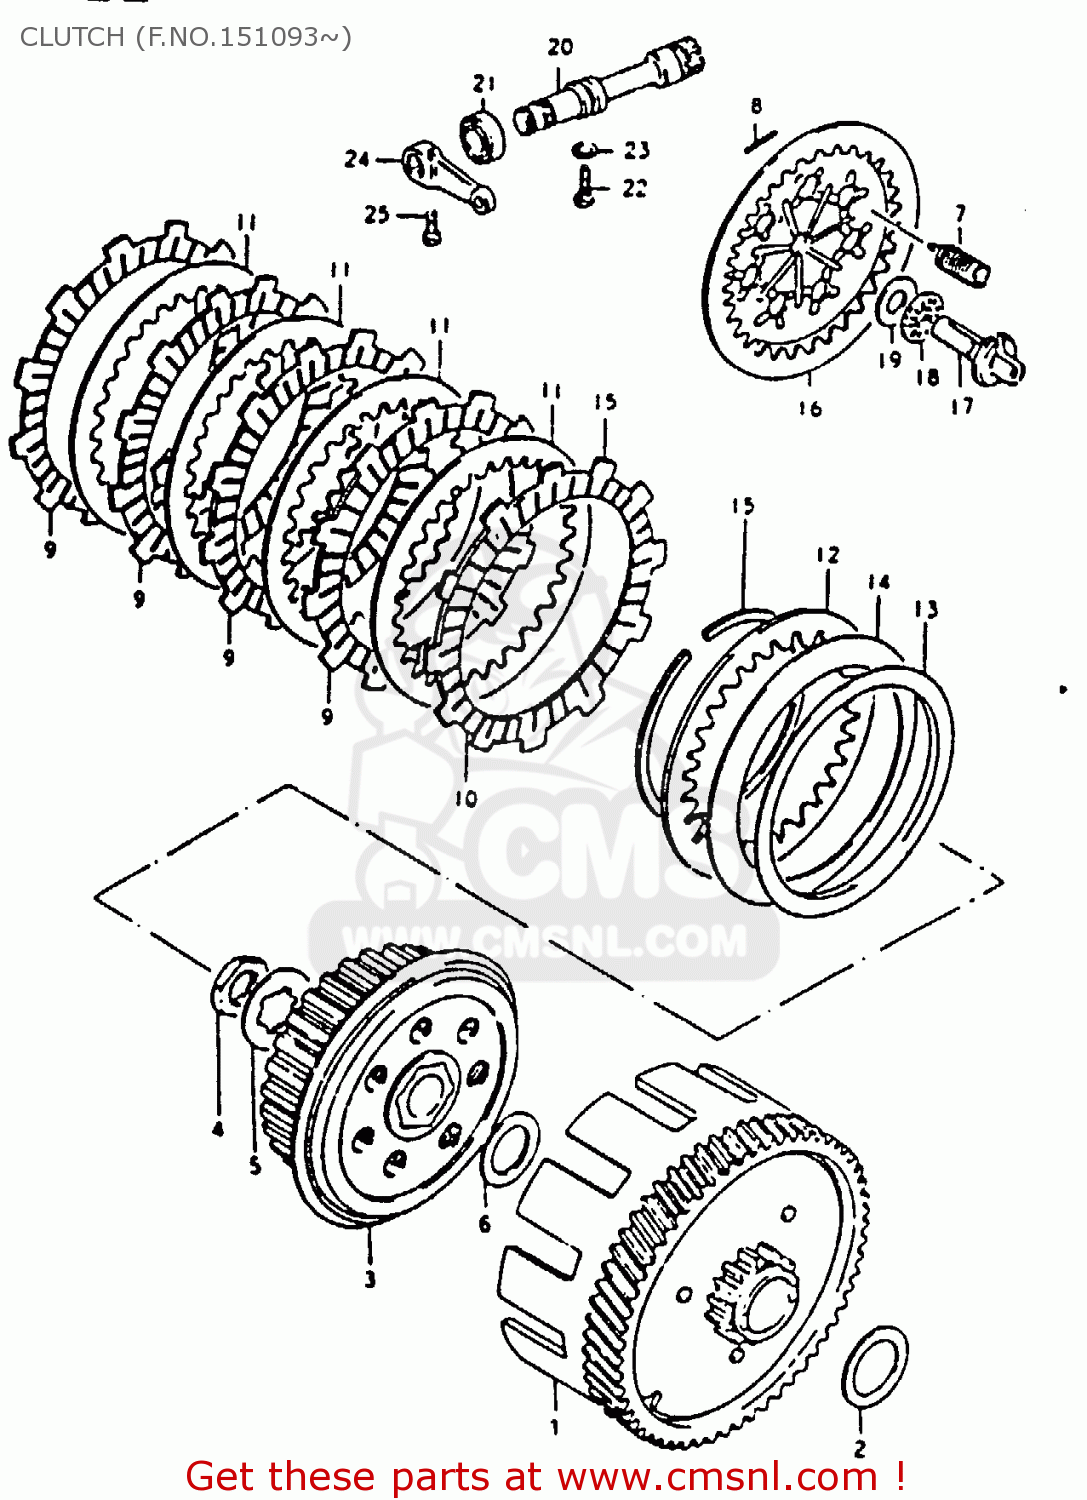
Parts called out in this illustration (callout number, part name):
1	GEAR ASSEMBLY,PRIMARY DRIVE
2	WASHER
3	HUB,CLUTCH SLEEVE
4	NUT
5	WASHER,LOCK
6	WASHER
7	SPRING
8	PIN(2.5X19.8)
9	PLATE,CLUTCH DRIVE
10	PLATE,CLUTCH DRIVE (MCA)
11	PLATE,CLUTCH DRIVEN (NAS)
12	PLATE,CLUTCH DRIVEN(T:2.0) (NAS)
13	SEAT,WAVE WASHER
14	WASHER
15	CIRCLIP
16	PLATE,CLUTCH PRESSURE
17	BACK,CLUTCH RELEASE
18	BEARING(10X22X2.8)
19	WASHER(10.1X21.4X0.8)
20	PINION,CLUTCH RELEASE
21	OIL SEAL
22	BOLT(6X12)
23	WASHER
24	ARM,CLUTCH RELEASE
25	BOLT
